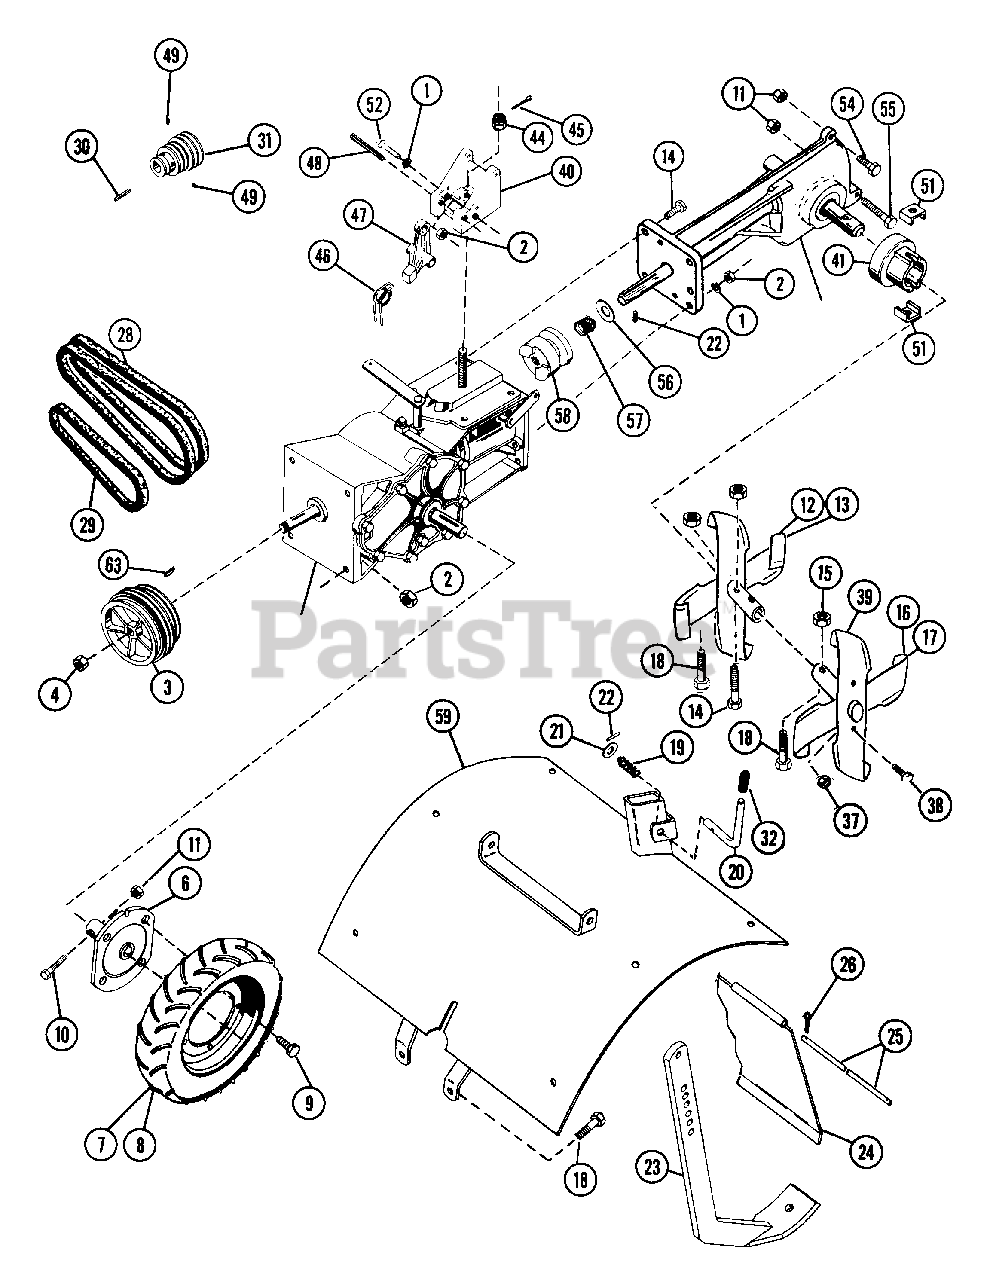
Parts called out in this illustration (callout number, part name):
1	WSHR-LK .375X.115 HVY PL
2	NUT-HEX .375-16
3	DRIVE SHEAVE
4	NUT-LK-CTR .75-16 PL
5	KEY-FTHR .25X1.875X.25 SAE
6	WHEEL HUB
7	R H TIRE AND RIM ASSY
8	L H TIRE AND RIM ASSY
9	BLT-WHL .50-20X.75 GR5 PL
10	BLT-HEX .31-18X2.00 PL GR2
11	NUT-LK .312-18 GR A PL
12	R H INNER TINE SPOOL
13	L H INNER TINE SPOOL
14	BLT-HEX .38-16X1.75 PL GR2
15	NUT-LK-CTR .375-16 GR A PL
16	R H OUTER TINE SPOOL
17	L H OUTER TINE SPOOL
18	BLT-HEX .38-16X2.00 PL GR2
19	SG-COMP .045X.50X1.187
20	DEPTH REGULATING PIN
21	WSHR-FL-STL .38X.875X.083 PL
22	PIN-ROLL .125X1.00
23	DEPTH SHOE
24	TAILBOARD
25	TAILBOARD PIN
26	PIN COTR .09X.50 PL
28	V-BELT, SAE 380-RAW EDGE (SET)
29	V-BELT, 3L-COGGED
30	KEY-SQ .25 X 1.25 X .25 SAE
31	ENGINE SHEAVE
35	KEY-FTHR .188X1.25X.187 SAE
37	KEY-FTHR .188X1.25X.187 SAE
38	BLT-HEX .44-14X1.00 GR5
39	L H TURBO-TINE
39	R H TURBO-TINE
40	HANDLEBAR BRACKET
41	DUST CAP
44	NUT-SL .50-13
45	PIN-COTR .12X1.0 PL
46	SG-TORS .109X.88X2.25
48	PIN-ROLL .313X2.00
49	SCR-SET .32-18X.38 SKHCUPNL OH
52	BLT-HEX .38-16X1.00 PL
54	BLT-HEX .31-18X1.25 PL GR2
55	BLT-HEX .31-18X3.50 PL GR2
56	WSHR-FL-STL .755X1.375X.125
57	SG-COMP .080X.97X2.18 WLD14
58	TILLER JAW CLUTCH
59	TINE HOOD W/DECALS
